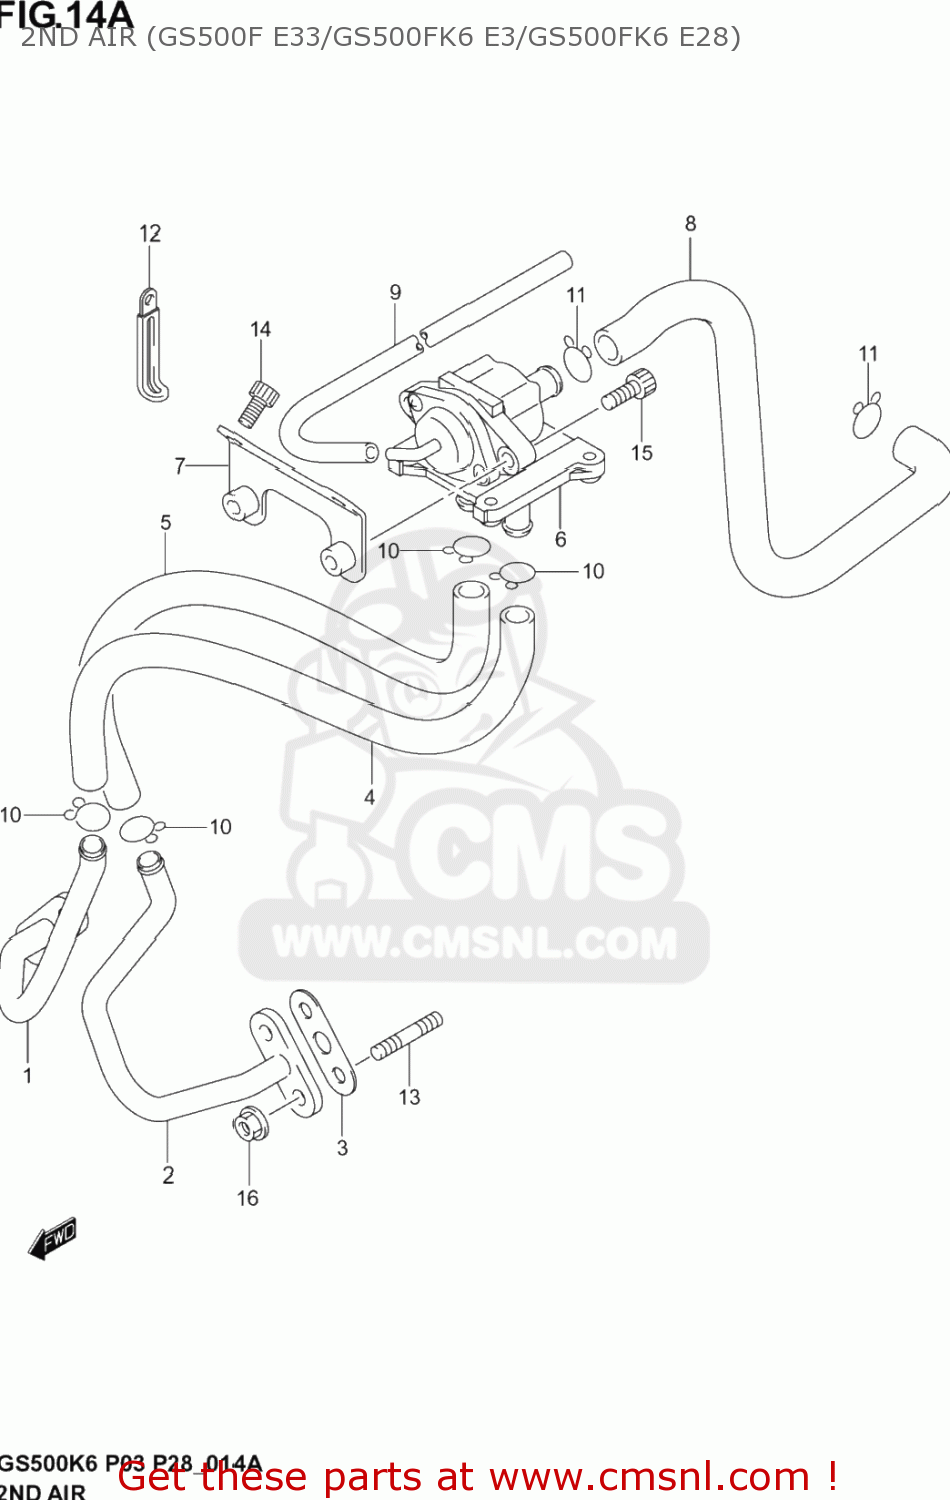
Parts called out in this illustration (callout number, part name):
1	PIPE,2ND AIR,R
2	PIPE,2ND AIR,L
3	GASKET,2ND AIR (NAS)
4	HOSE , 2ND AIR REED VALVE RH
5	HOSE , 2ND AIR REED VALVE LH
6	VALVE ASSY,2ND AIR
7	BRACKET,2ND AI
8	HOSE, 2ND AIRC
9	HOSE(4X7X600)
10	CLIP
11	CLIP
12	CLAMP(L:45)
13	STUD BOLT
14	BOLT OIL LEVEL
15	BOLT
16	NUT
